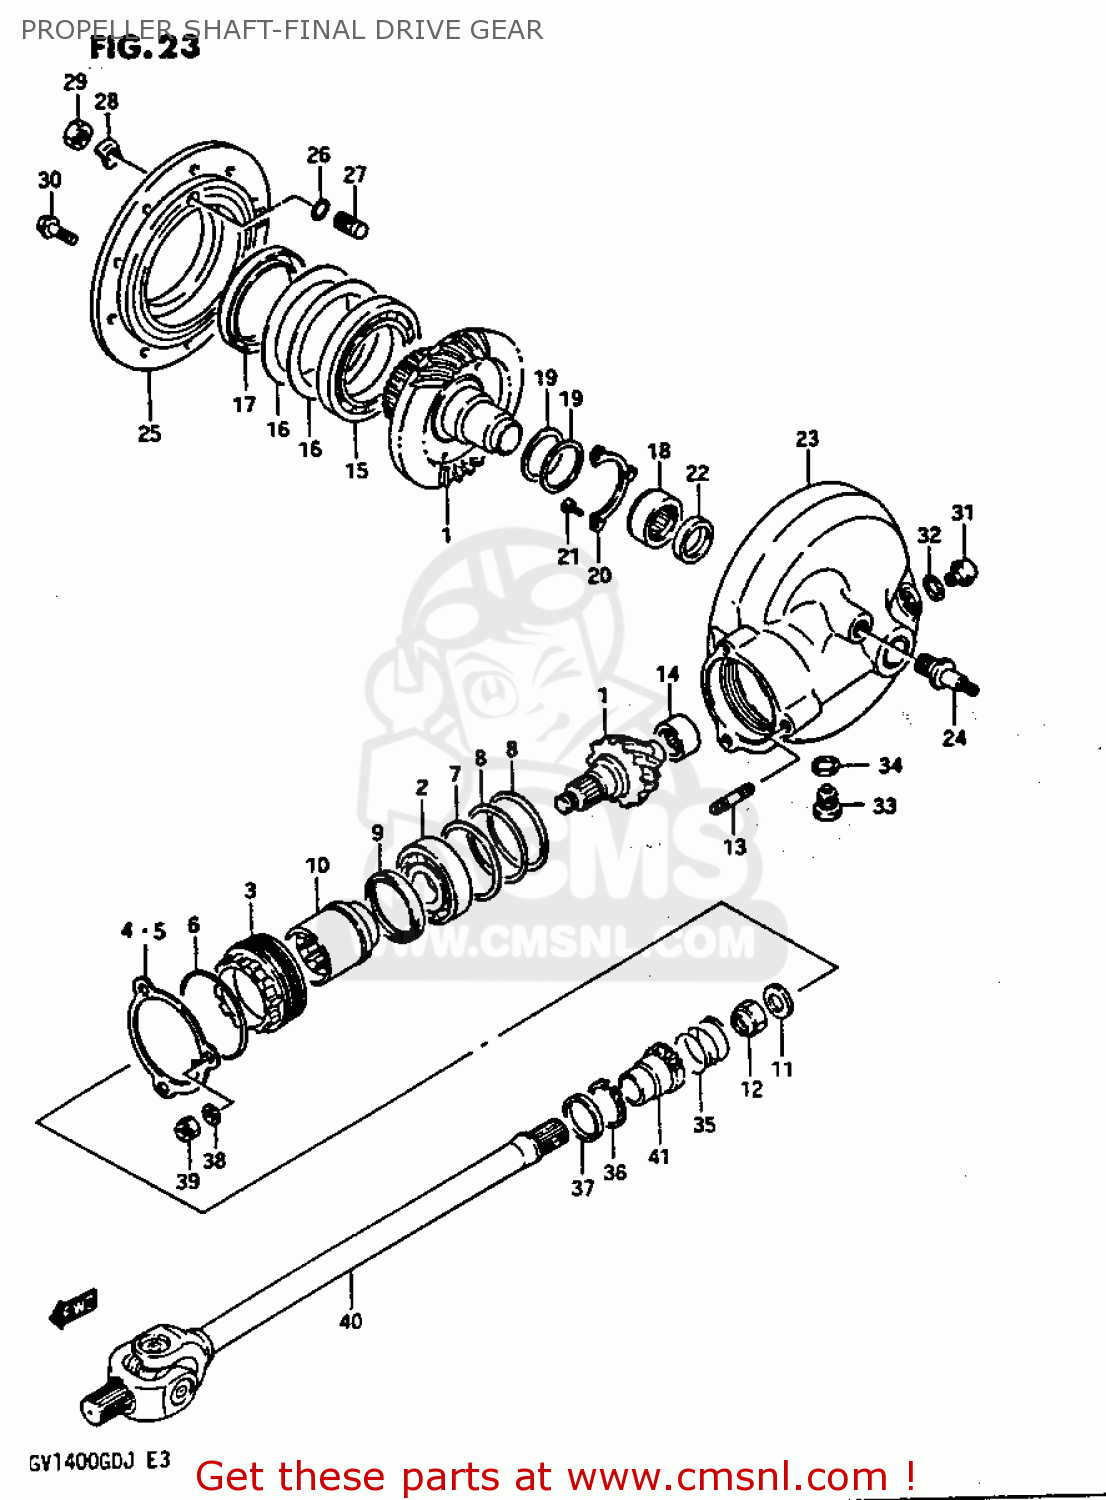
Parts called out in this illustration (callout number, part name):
1	GEAR,FINAL DRIVE BEVEL
2	BEARING(28X68X18)
3	STOPPER,FINAL DRIVE BEARING
4	PLATE,BEARING STOPPER
5	PLATE,BEARING STOPPER
6	O RING(D:2.1,ID:66.2)
7	WASHER(54X68X1.5)
8	SHIM,FINAL DRIVE GEAR 62
9	SEAL,OIL
10	COUPLING,FINAL DRIVE GEAR
11	WASHER(16X29X4)
12	NUT
13	STUD 10X25
14	BEARING(20X34X18)
15	BEARING(70X110X13)
16	SHIM,DRIVEN GEAR BEARING
17	SEAL,OIL(70X96X16)
18	BEARING(35X48X23.7)
19	SHIM,FINAL DRIVEN GEAR
20	RETAINER,FINAL DRIVEN GEAR BRG
21	SCREW 6X12
22	SEAL,OIL(30X42X7)
23	CASE,FINAL GEAR
24	STUD
25	CASE,FINAL GEAR BEARING
26	O RING(D:1.9,ID:9.8)
27	BOLT,FINAL DRIVEN GEAR THRUST
28	WASHER (54X68X1.5)
29	NUT 12MM
30	BOLT 8X30
31	PLUG(14X12)
32	GASKET(14X19.2X2) (NAS)
33	PLUG
34	GASKET(14X19.2X2) (NAS)
35	SPRING
36	CIRCLIP
37	SEAL,OIL(30X40.5X5.5)
38	LOCK WASHER
39	NUT
40	SHAFT,PROPELLER
41	COUPLING,PROPELLER SHAFT
